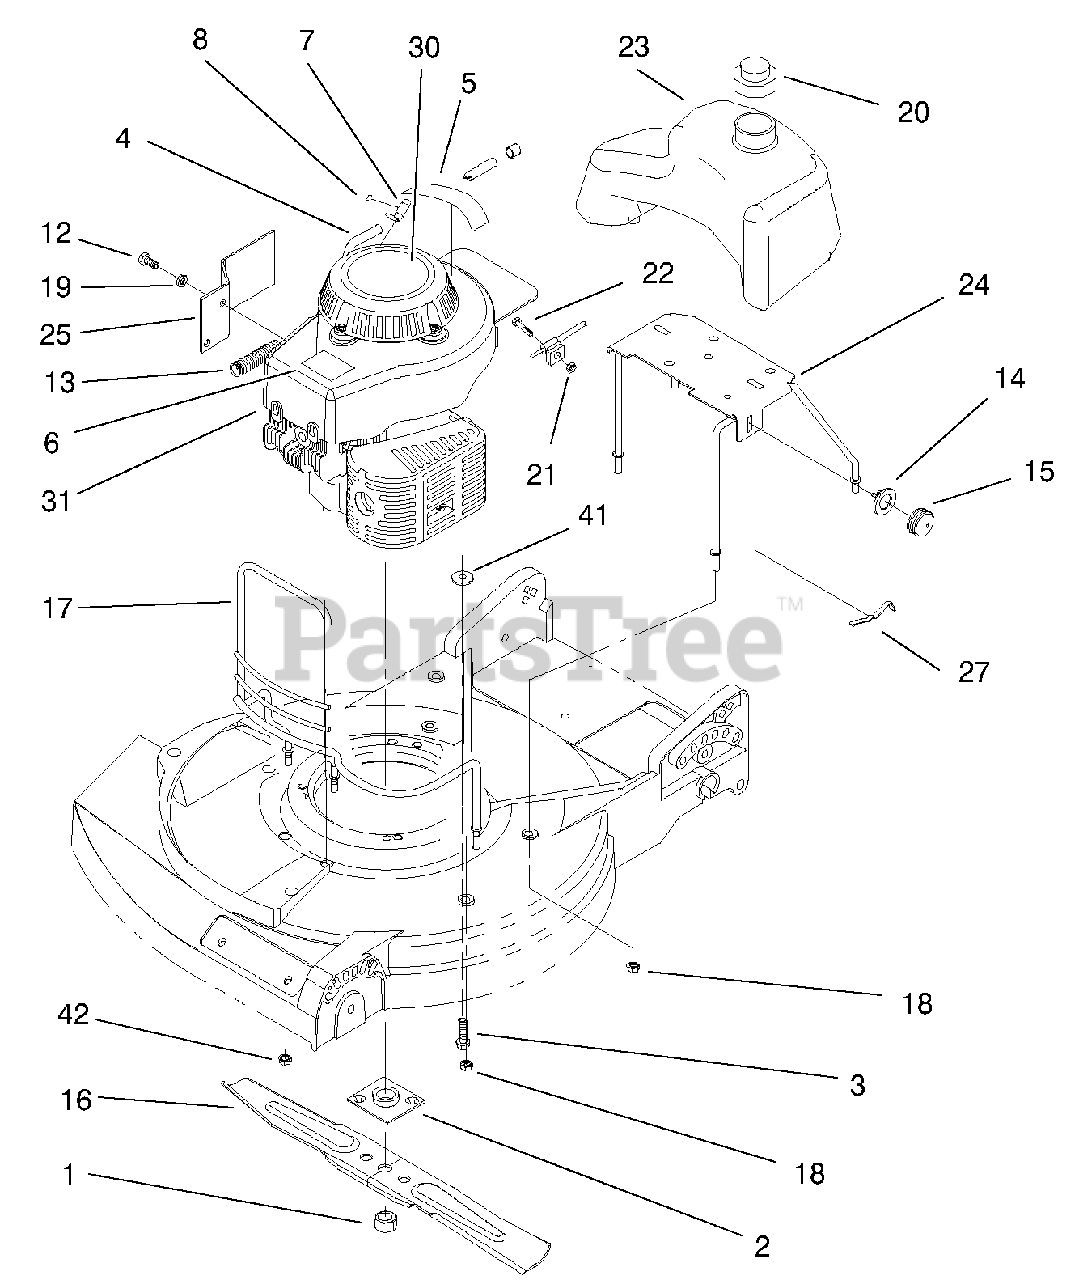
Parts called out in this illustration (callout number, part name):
1	Nut-Blade
2	Plate & Collar ASM
3	Screw-Sems
4	Fuel Line
5	Decal-Fuel Mix
6	Decal-Lawn Boy
7	Stop-Rope
12	Screw-HH
13	Spring-Compression
14	Body-Primer
15	Bulb-Primer
16	Blade
17	Guard-Muffler
18	Nut-Lock
20	Cap ASM-Fuel/Oil
21	Nut-Hex
23	Tank-Fuel
24	Tank Bracket ASM
25	Guard-Brake
30	Decal-Recoil
31	Engine ASM
41	Washer-Hood Pivot
42	Nut-Lock, NI
